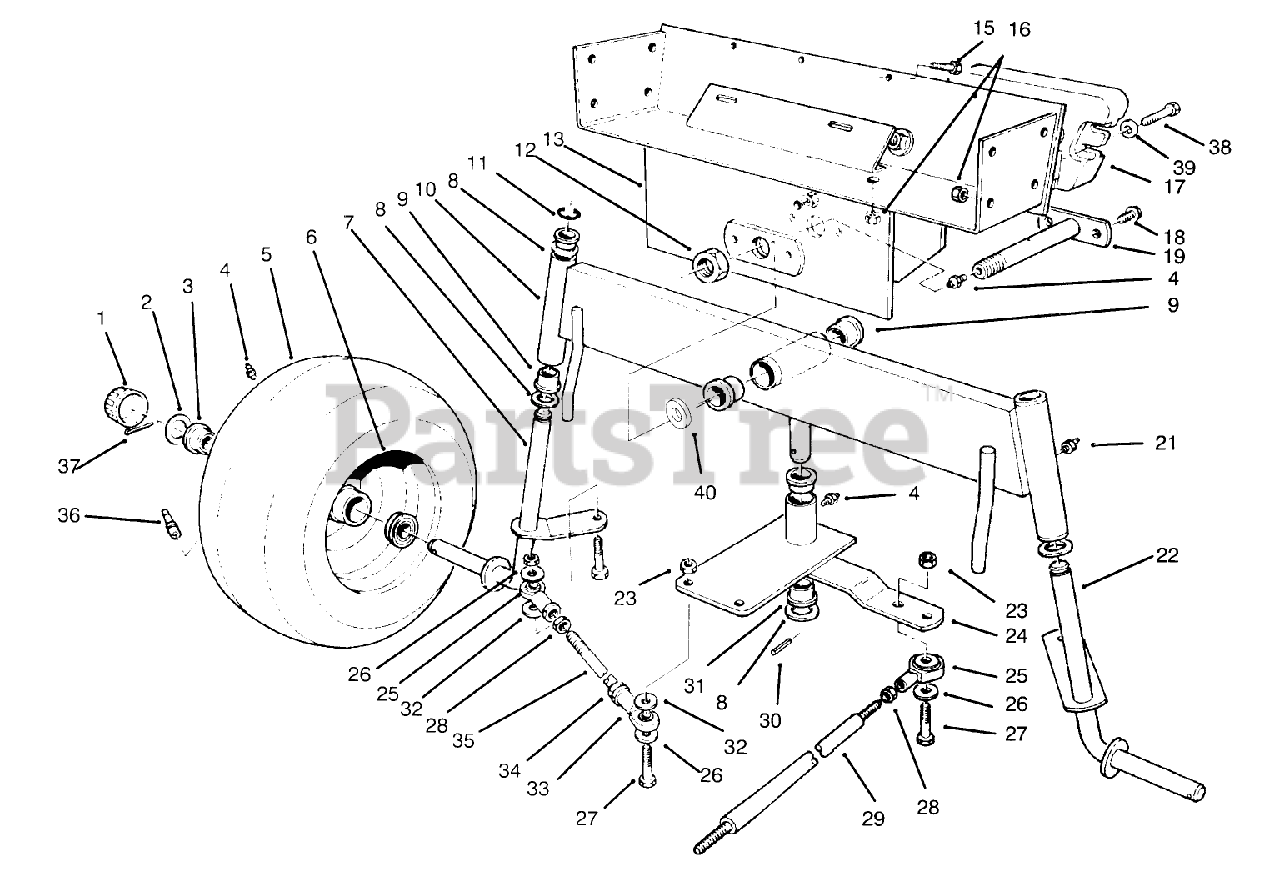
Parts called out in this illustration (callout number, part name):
1	CAP-HUB
2	WASHER-PLAIN
3	Bearing
4	FITTING-GREASE
6	FRONT WHEEL
7	Spindle R.H.
8	WASHER-THRUST
9	BUSHING PM
10	Axle-Rear (Incl. Ref. #9 & 20)
11	E-RING
12	NUT-LOCK NI
13	Frame-Rear
15	SCREW-HH
16	NUT-LOCK, NI
17	WEIGHT-REAR
18	SCREW-HHFTF
19	Axle-Pivot
21	GREASE FITTING
22	Spindle LH.
23	NUT-LOCK, NI
24	Plate-Pivot (Incl. Ref. #4 & 30)
25	BALL JOINT RH
26	WASHER-FLAT
27	SCREW-HH
28	NUT-JAM
29	Rod-Steering
30	PIN-ROLL
31	BEARING-FLANGE
32	WASHER
33	BALL JOINT LH
35	TIE ROD - STEERING
36	STEM-VALVE
37	PIN-COTTER
38	SCREW-HH
39	WASHER-LOCK
40	WASHER-FLAT
